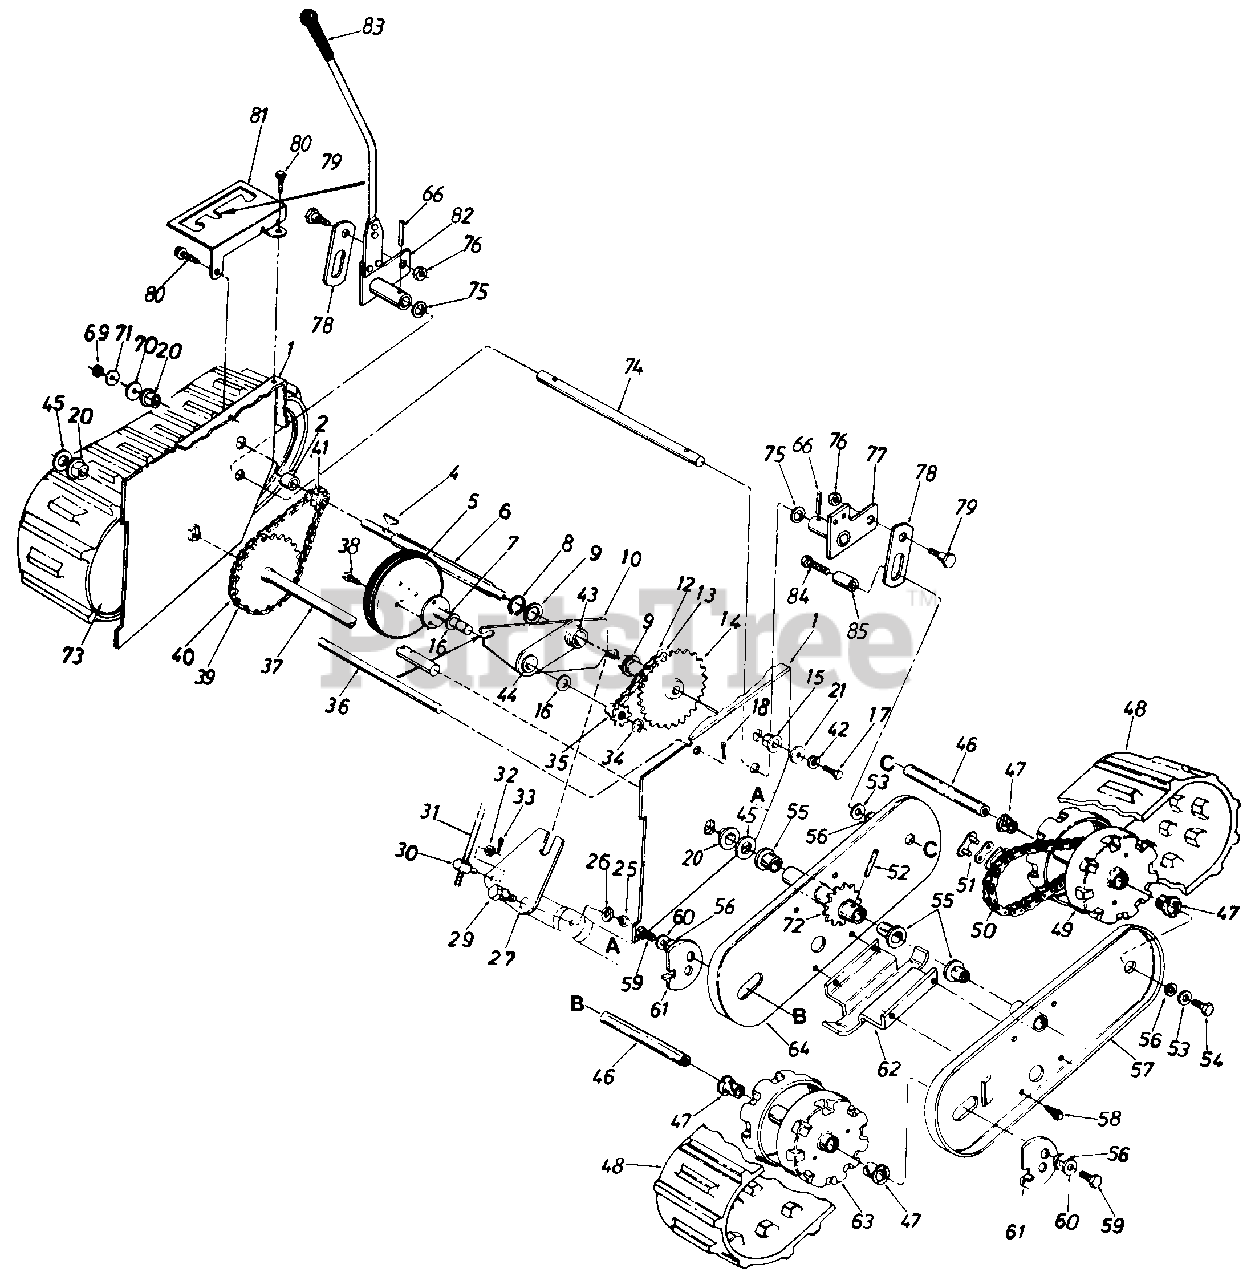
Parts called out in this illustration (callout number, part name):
1	Frame Ass'y.
2	Spacer .50" I.D. x .75" O.D. x.78" Lg.
4	#4 Hi-Pro Key 3/32 x 518" Dia.
5	Friction Wheel Ass'y.
6	Hex Shaft
7	Friction Wheel Mounting Plate Ass'y.
8	Snap Ring 1.00" Dia. Shaft
9	Fl-Wash. 1.00" x 1.63" O.D. x .03
10	Sliding Bracket Ass'y.
12	#41 Chain 1/2" Pitch x 35 Links
13	Master Link for #41 Chain
14	32 Teeth Sprocket Ass'y.
15	Hex Flange Brg. .630" I.D.
16	Fl-Wash. .62" I.D. x 1.00" O.D. x .06
17	Hex Lock Bolt 5/16-18 x .62" Lg.
18	Cotter Pin 3132" Dia. x .75" Lg.
20	Flange Brg. w/Flats .75" I.D.
21	Fl-Wash. .34" I.D. x 1.12" O.D. x .1 25
25	Hex Jam Nut 3/8-16 Thd.
26	L-Wash. 318" I.D.*
27	Shifting Linkage Bracket
29	Shld. Bolt .625" Dia. x .170" Lg.
30	Adjustment Ferrule
31	Shifting Rod 5116" Dia. x 32.50" Lg.
32	Fl-Wash. .34" I.D. x .64" O.D. x .06
33	Cotter Pin 3132" Dia. x .75" Lg.
34	Snap Ring .562" Dia. Shaft
35	Sprocket 7 Teeth x .50" Pitch
36	Shaft .50" Dia. x 9.50" Lg.
37	32 Teeth Wheel Shaft Ass'y.
38	Hex Wash. Hd. Self-Tap Scr. 5/16-24 x .50" Lg.
39	#420 Chain 112" Pitch x 39 Links
40	Master Link for #420 Chain
41	8 Teeth Center Sprocket
42	L-Wash. 5/16" I.D.
43	Plastic Bearing
44	Bronze Bearing
45	Fl-Wash. .76" I.D. x 1.49 O.D.
46	Wheel Shaft 5/8 x 4.25" Lg.
47	Flange Brg. .632" I.D.
48	Snow Track 5" x 48"
49	Drive Wheel Ass'y.
50	Chain #420 x 50 Pitch x 37 Links
51	Master Link #420
52	Spring Pin Spir. 1/4" Dia. x 1.50" Lg.
53	Bell-Wash. .345" I.D. x .88" O.D.
54	Hex Bolt 5/16-24 x .62" Lg.
55	Flange Brg. .757" I.D.
56	Fl-Wash. .510" I.D. x 1.0" O.D.
57	Outer Plate Ass'y.-L.H.
57	Outer Plate Ass'y.-R.H.
58	Hex Wash. S-Tap Scr. 1/4-20 x.50" Lg.
59	Hex Bolt 5/16-24 x .62" Lg.
60	Bell-Wash. .345" I.D. x .88" O.D.
61	Track Adjuster
62	Skid Shoe
63	Idler Wheel Ass'y.
64	Inner Plate Ass'y.-L.H.
66	Spring Pin 1/4" x 1.25" Lg.
69	Hex Ins. L-Nut 1/2-20 Thd.
70	Fl-Wash. .53 I.D. x 1.25 O.D. x .10
71	Bell-Wash. .50 I.D. x 1.0 O.D. x .075
72	17T Sprocket Hub Ass'y.
73	Inner Plate Ass'y.-R.H.
74	Track Lock Axle
75	Fl-Wash. 5/8 I.D. x 1" O.D.
76	Hex L-Nut 3/8-16 Thd.
77	Pivot Arm Ass'y.-L.H.
78	Slotted Link
79	Shld. Bolt .625" Dia. x .217
80	Hex Wash. AB-Tap Scr. 5/16 x .75" Lg.
81	Position Selector Plate
82	Track Lock Handle Ass'y.
83	Grip
84	Hex Bolt 5/16-24 x 1.25" Lg. Gr. 5
85	Spacer.325" I.D.
